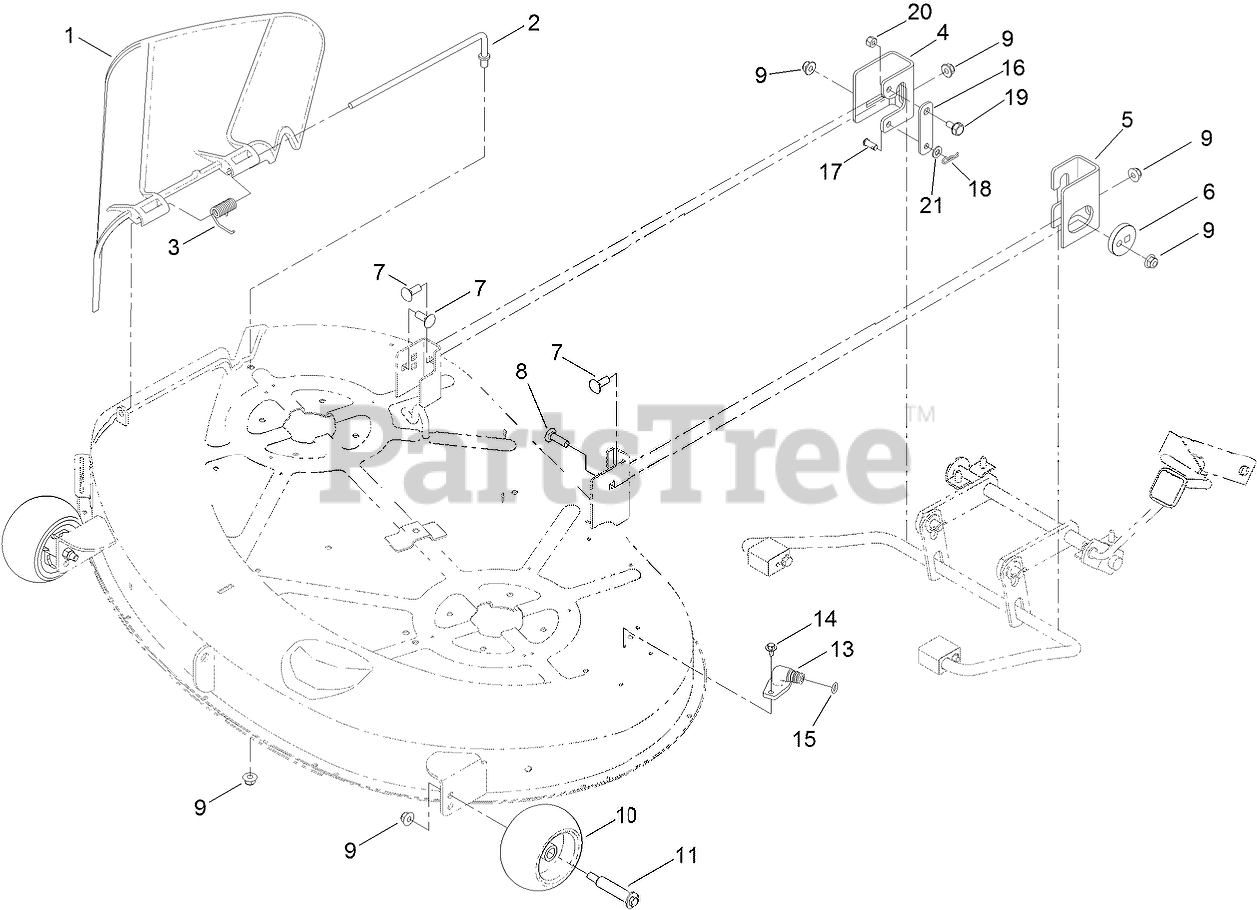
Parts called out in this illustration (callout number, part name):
1	DEFLECTOR
2	ROD-PIVOT
3	SPRING-TORSION
4	BRACKET-HANGER, RH
5	BRACKET-HANGER, LH
6	ECCENTRIC
7	BOLT-CARR
8	SCREW-CARR
9	NUT-HF, NI
10	ROLLER-SCALP, ANTI
11	BOLT-SHOULDER
13	FITTING-WASHOUT
14	SCREW-HHFTF
15	O-RING
16	BRACKET-DECK SUPPORT
17	PIN-CLEVIS
18	PIN-COTTER
19	BOLT-SHOULDER
20	NUT-LOCK, NI
21	WASHER-PLAIN
